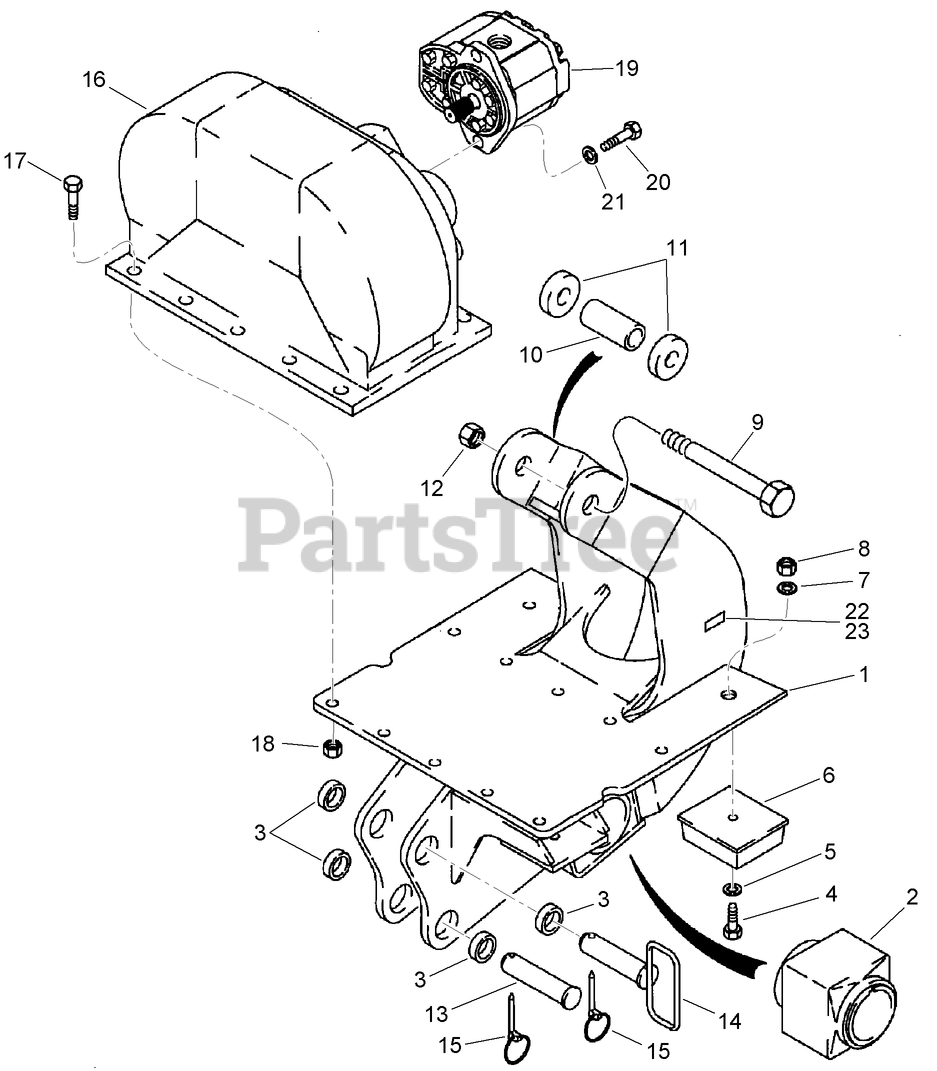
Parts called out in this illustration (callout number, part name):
1	FRAME-plow gearbox mounting
2	JOINT-CENTER, BONDED RUBBER
3	BUSHING-plow frame
4	BOLT
5	WASHER-FLAT
6	BUMPER
7	WASHER-FLAT
8	NUT-HEX
9	BOLT-hex, 1 NC x 7 inch
10	SPACER-bushing, 38 mm OD x 87 mm long
11	BUSHING-cylinder mounting
13	PIN-clevis, 1-1/8 x 4-7/8 inch long
14	PIN-with handle, 28 x 114 mm, plow blade
15	PIN-KLIK
16	BOX-SHAKER
18	NUT-HEX
19	MOTOR ASSEMBLY - Plow
20	SCREW-HH
22	PLATE - Serial Number
23	TACK-FASTENER, STEEL
